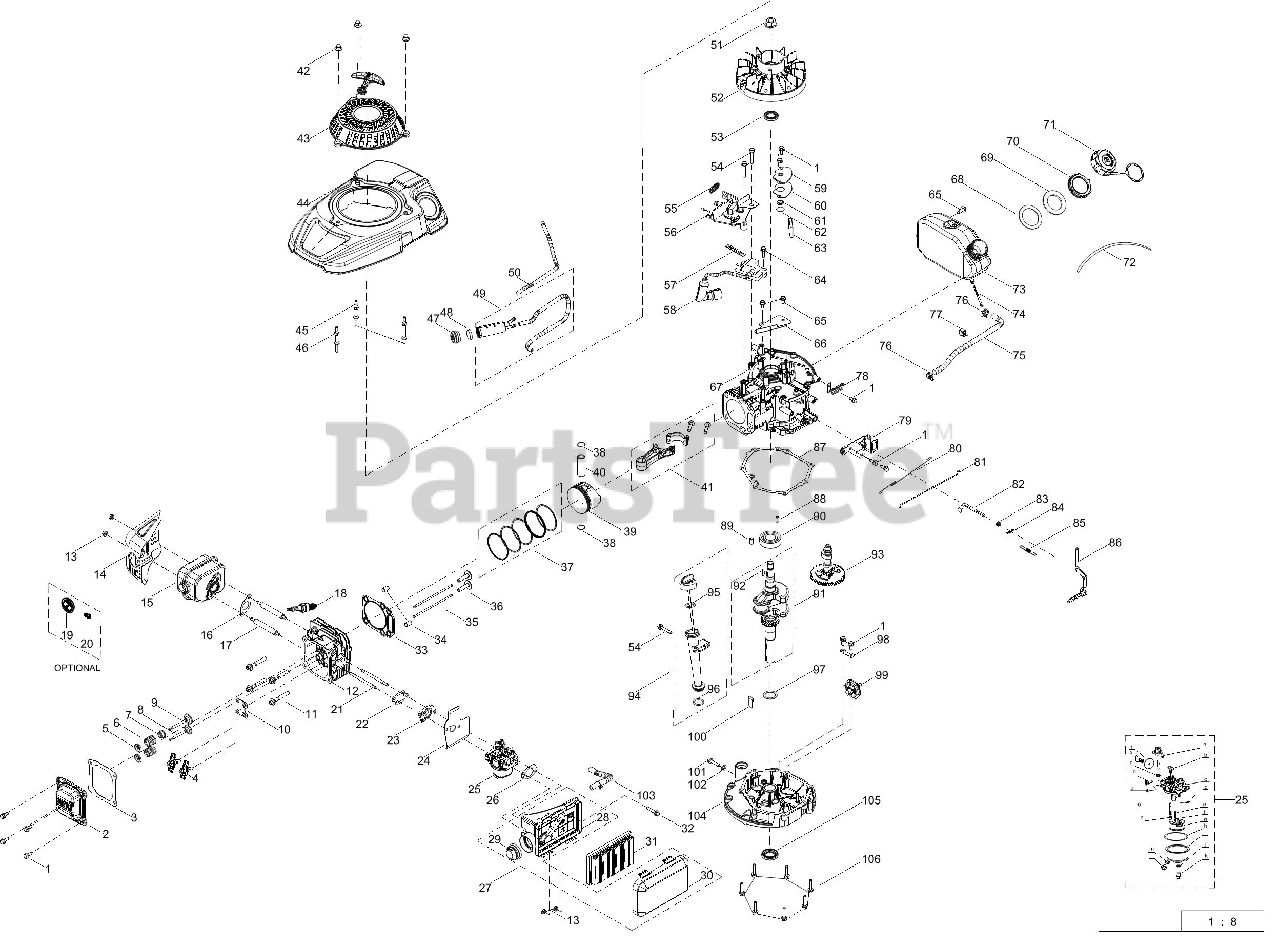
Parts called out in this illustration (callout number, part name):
1	Bolt M6x14
2	Valve Cover
3	Valve Cover Gasket
4	Rocker Arm Assembly
5	Valve Spring Retainer
6	Valve Spring
7	Intake Valve Seal
8	Exhaust Valve
9	Intake Valve
10	Push Rod Guide
11	Bolt M8x54 Cylinder Head
12	Cylinder Head
14	Muffler Shield
15	Muffler Assembly
16	Muffler Gasket
17	Muffler Stud M6x95
18	Spark Plug/F5RTC
19	Spark Arrestor
20	Spark Arrestor Screw
21	Carb Stud M6x87
22	Carburetor Gasket
23	Carburetor Insulator
24	Carburetor Gasket
25	Carburetor Assembly
26	Air Filter Base Gasket
27	Air Filter Assembly
28	Air Filter Base
29	Primer Bulb, Non-Vented
30	Air Filter Cover
31	Air Filter Element, Paper
32	Bolt M6x30
33	Cylinder Head Gasket
34	Cylinder Head Dowel Pin 10x16
35	Push Rod
36	Tappet
37	Piston Ring Set
38	Piston Pin Snap Ring
39	Piston
40	Piston Pin
41	Connecting Rod Assembly
42	Starter Acorn Nut
43	Starter Recoil Assembly
44	Engine Shroud Assembly
45	Shroud Stud M6x78.5
46	Shroud Stud M6x74
47	Carbon Canister Filter Cap
48	Carbon Canister Filter
49	Carbon Canister Assembly
50	Carbon Canister Purge Hose
51	Flywheel Nut M14
52	Flywheel
53	Upper Crankshaft Seal
54	Bolt M6x35
55	Brake Spring
56	Brake Assembly
57	Flexible Clamp
58	Ignition Coil Assembly
59	Breather Cover Plate
60	Breather Gasket
61	Breather Valve Spring
62	Breather Valve
63	Breather Screen
64	Bolt M6x20
65	Bolt M6x12
66	Air Vane Cover Plate
68	Fuel Tank Lower Grommet
69	Fuel Tank Upper Grommet
70	Fuel Tank Nut
71	Fuel Cap Assembly
72	Plastic Tie 150Mm
74	Fuel Filter
76	Fuel Hose Clamp
77	Plastic Support Clamp, Hose
78	Flexible Clamp
79	Component Bracket
80	Throttle Linkage Spring
81	Throttle Linkage
82	Governor Arm Shaft
83	Governor Seal
84	Governor Arm Shaft Cotter Pin
85	Governor Spring
86	Governor Arm Assembly
87	Crankcase Cover Gasket
88	Crankcase Cover Dowel Pin 7x14
89	Crankcase Cover Dowel Pin 9x14
90	Main Bearing
91	Crankshaft Assembly
92	Flywheel Key
93	Camshaft Assembly
94	Dipstick Assembly
95	Dipstick / Oil Fill Tube O-Ring
96	Dipstick / Oil Fill Tube O-Ring
97	Crankshaft Thrust Washer
98	Governor Gear Mounting Plate
99	Governor Gear/Shaft Assembly
100	Oil Return Seal
101	Oil Drain Plug
102	Oil Drain Plug Washer
103	Breather Hose Assembly
104	Crankcase Cover
105	Lower Crankshaft Seal
106	Bolt M6x28
